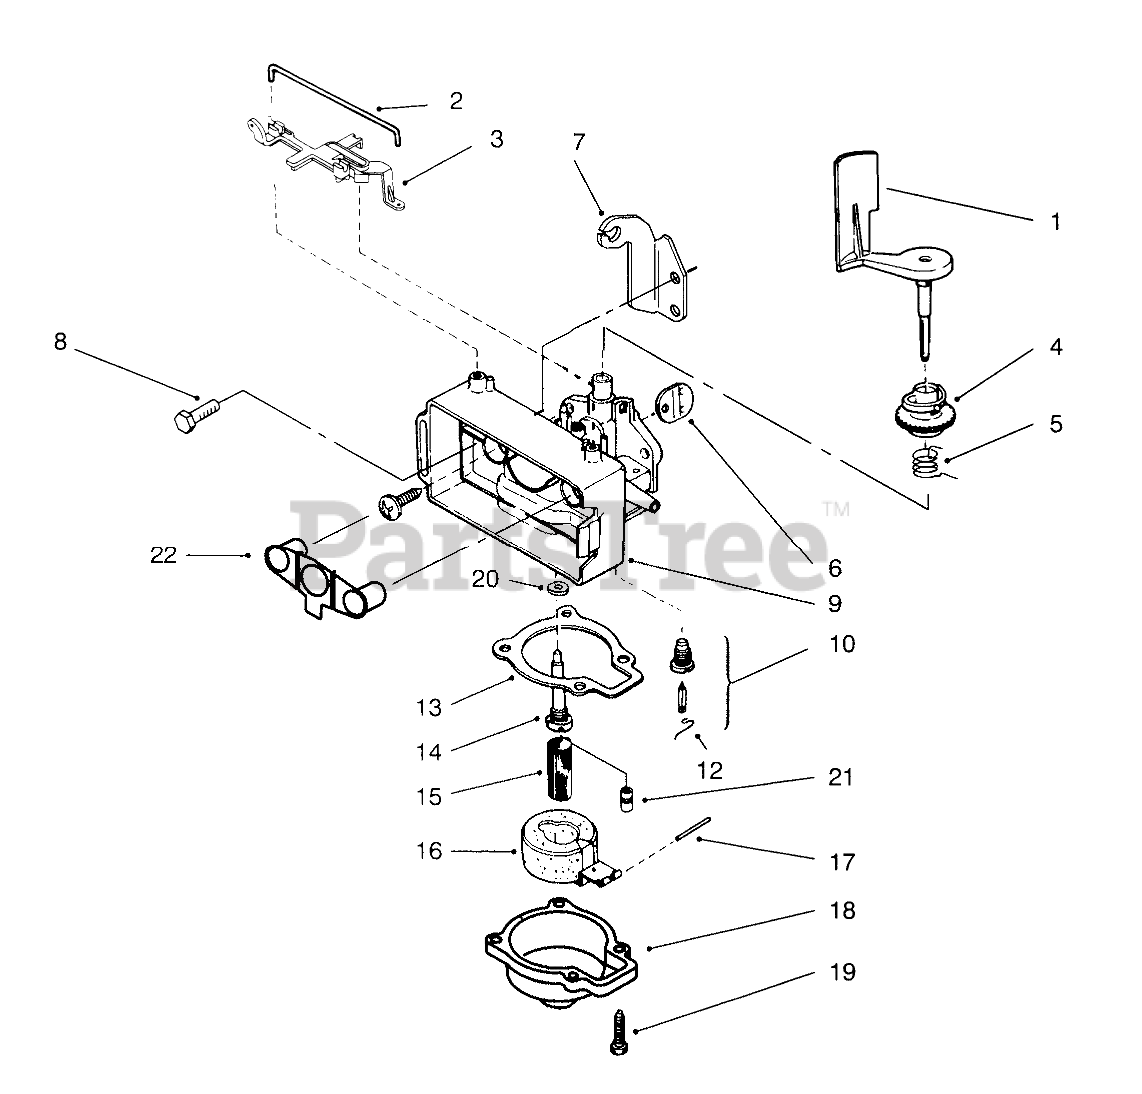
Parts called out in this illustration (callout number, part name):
1	Air Vane&shaft
2	RETAINER
3	LEVER-ADJ. VF
4	COLLAR-ADJUST, AIRVANE
5	SPRING-GOV V
6	DISC-THRO. V
7	BRKT-THRO.CONT V
8	SCREW V
9	CARB. BODY V
10	Kit-Float Valve, Body & Seat (Incl. Ref. #12)
14	NOZZLE VF
15	FILTER-FUEL VS
16	FLOAT & ARM ASM
17	PIN-STRAIGHT
18	CHAMBER-FLOAT
19	SCREW-HH
20	WASHER
21	JET-MAIN VF
22	SHIELD-FUEL V
